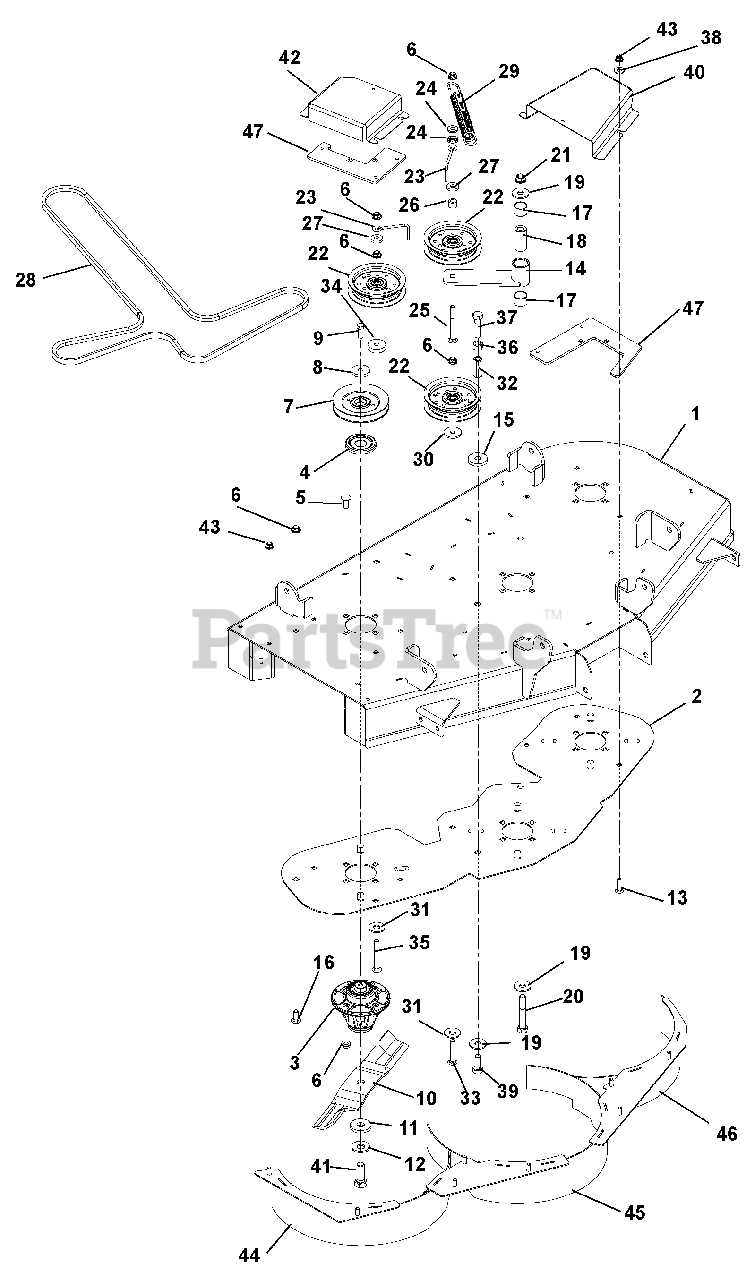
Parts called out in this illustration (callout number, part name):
1	XL-42 DECK KIT WITH DECALS
2	DOUBLER PLATE, 42 XL
3	SPINDLE ASSEMBLY
4	DUST CAP
5	@BLT-RDHDSQNK .38-16X1.25 G5YZ
5	@BLT-RDHDSQNK .38-16X1.50 G5YZ
6	@NUT-LK-NYL-FLG .38-16 YWZC
7	PULLEY, SPINDLE
8	WSHR,FLT STL.406X1.50X.245YWZC
9	BLT-HEX .38-16X1.0 GR8 YZ EP30
10	BLADE, MULCH 14.50"
11	WSHR-FLT .640X1.75X.250
12	WSHR-BLVL .669X1.535X.138
13	BLT-SERHFWH .312-18X.50 YWZC
14	WELDMENT, IDLER ARM
15	WSHR-FL-STL .515X1.625X.250 YZ
16	@BLT-RDHDSQNK .38-16X1.00 G5YZ
17	BRG, 1.00 X 1.12 X .75
18	BSHG, SPCR .502X.997X2.03 PM
19	WSHR-FL-STL.511X1.441X.125 YWZ
20	@BLT-HEX .50-13X3.50 GR5 YWZC
21	@NUT-LK-NYL-FLG .50-13 YWZC
22	ASM, IDLER 4"
23	BELT FINGER
24	BSHG-FLG .406X.88X.270X.140
25	@BLT-RDHDSQNK .38-16X3.50 G5YZ
26	BSHG-SLV .391X.688X.52 PM
27	WSHR-FL-STL .406X1.00X.188 YWZ
28	V-BELT, HA-WRAPPED
29	EXTENSION SPRING
30	WSHR-FL-STL .390X1.5X.125 YWZC
31	PLATE,IDLER MNT REINFORCEMENT
32	NUT, COUPLING 1/2-13X1.75 YWZC
33	@BLT-RDHDSQNK .38-16X2.25 G5YZ
34	SPACER, .39 X 1.50 X .380
35	@BLT-RDHDSQNK .38-16X3.50 G5YZ
36	@NUT-HEX .50-13 YWZC
37	@BLT-HEX .50-13X2.00 GR5 YWZC
38	@WSHR-FL-STL.38X.875X.083 YWZC
39	@BLT-HEX .50-13X1.25 GR5 YWZC
40	BELT COVER, LEFT
41	BLT-HEX .62-18X1.75 GR8 YWZC
42	BELT COVER, RIGHT
43	@NUT-LK-NYL-FLG .31-18 YWZC
44	WMT, 42 MULCH BAFFLE (RH)
45	WMT, 42 MULCH BAFFLE (CTR)
46	WMT, 42 MULCH BAFFLE (LH)
47	BRKT, BELT COVER MOUNT - LHS
47	BRKT, BELT COVER MOUNT - RHS
